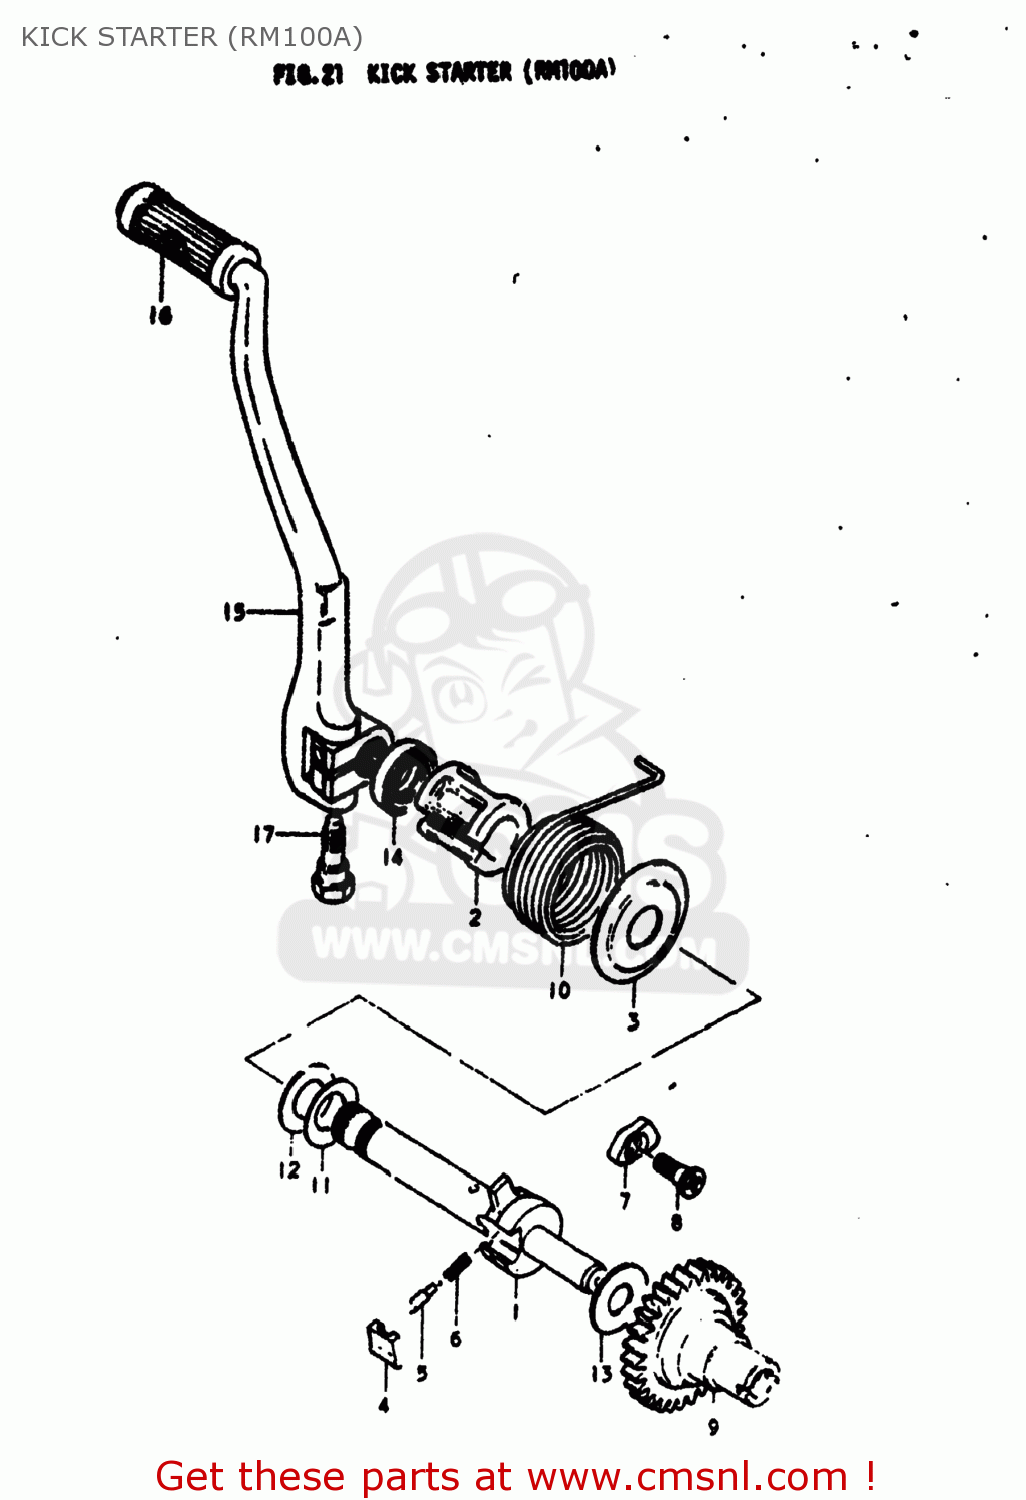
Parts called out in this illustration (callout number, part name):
1	SHAFT,KICK STARTER
2	GUIDE,KICK STARTER SFT SPRING
3	HOLDER,KICK STARTER SHAFT SPR
4	PAWL,KICK STARTER
5	PIN(5X15.5)
6	SPRING
7	LIFTER,KICK STARTER PAWL
8	SCREW(6X19)
9	GEAR,KICK STARTER DRIVE
10	SPRING
11	WASHER(16X30X0.5)
12	WASHER
13	WASHER
14	SEAL,OIL(16X30X8)
15	LEVER ASSY,KICK STARTER
16	RUBBER,KICK STARTER PEDAL
17	BOLT
